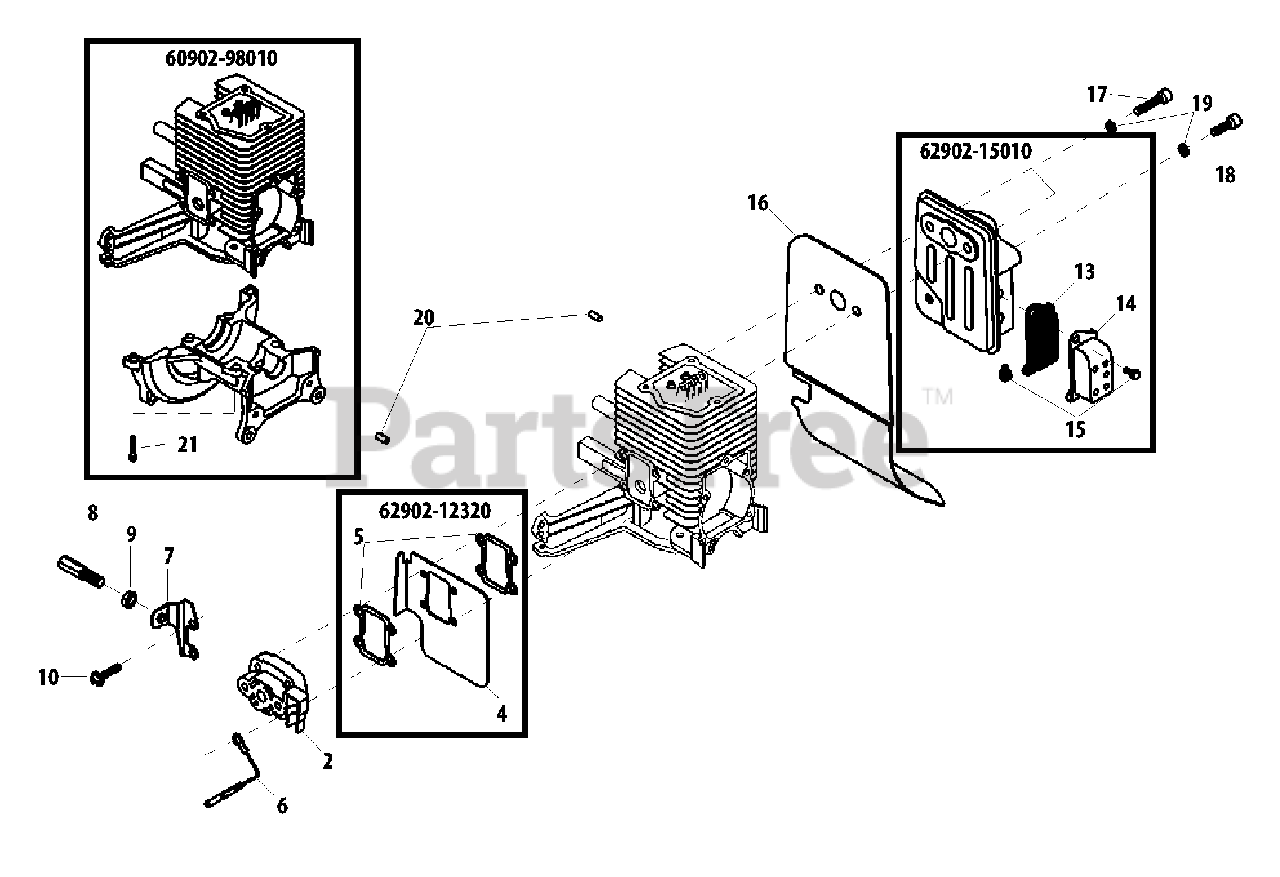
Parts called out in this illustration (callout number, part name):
2	INSULATOR WITH REED VALVE
4	HEAT SHIELD, INTAKE
5	GASKET, EXHAUST
6	LEAD - GROUND L= 110 MM
7	BRACKET, THROTTLE CABLE
8	ADJUSTER, THROTTLE CABLE
9	NUT, ADJUSTER LOCK M6
13	SCREEN, SPARK ARRESTER
14	GUIDE, EXHAUST
15	SCREW M4×6
16	HEAT SHIELD, EXHAUST
17	BOLT M5×25
18	BOLT 5×16
19	WASHER, FLAT 5.5×10×0.8
20	PIN, LOCATING Ø4×8
21	BOLT 5×16
60902-98010	CYLINDER BLOCK SET
62902-12320	SHIELD ASSY, INTAKE HEAT
62902-15010	MUFFLER ASSY
